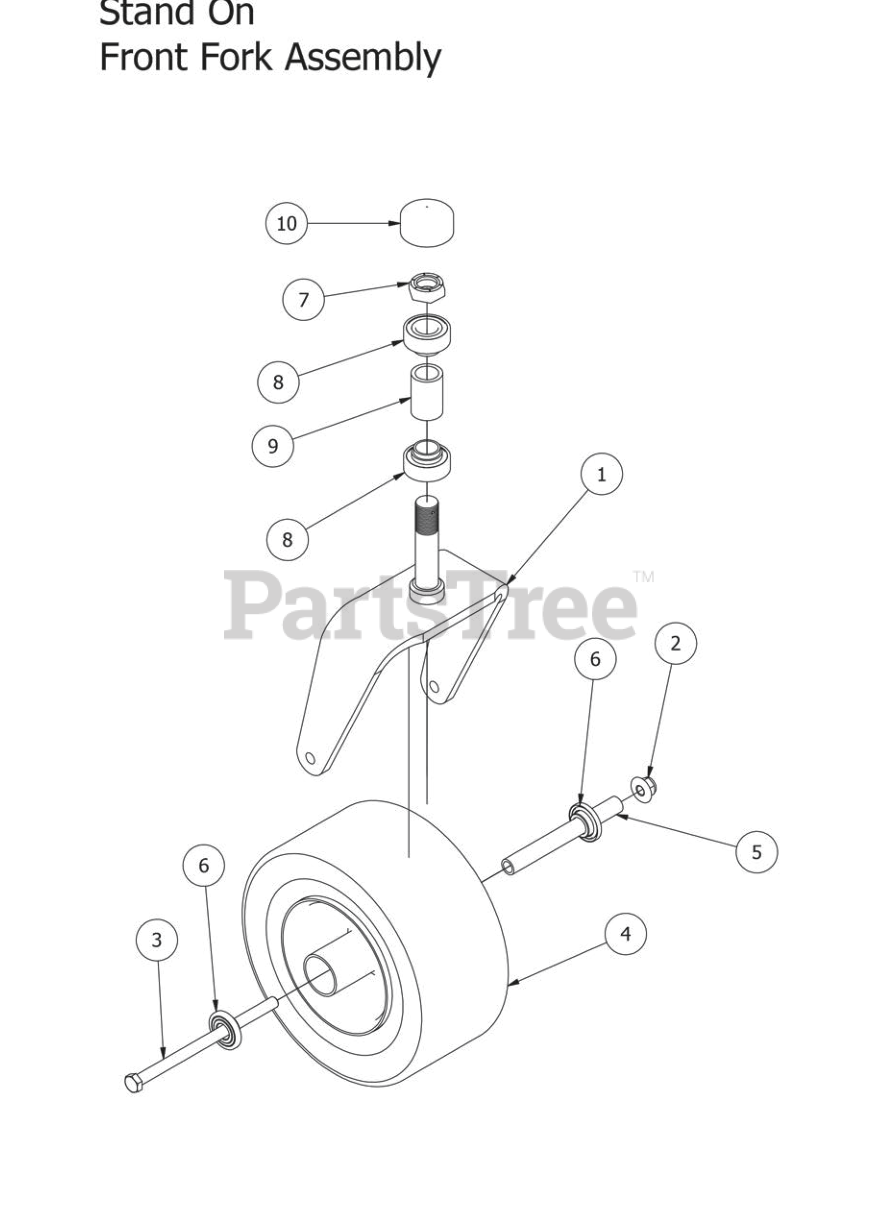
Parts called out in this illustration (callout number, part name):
1	Front Fork
2	1/2-13 Nylon Flange Nut-Orange
3	1/2" x 9" Bolt
4	Tire and wheel assembly
5	Front Wheel Spanner
6	Wheel Bearing
7	1" Fine Thread Nut
8	Caster Bearing -MZ, 2009 & up
9	ZT/CZT Caster Bearing Spacer
10	Rubber Bearing Cap
